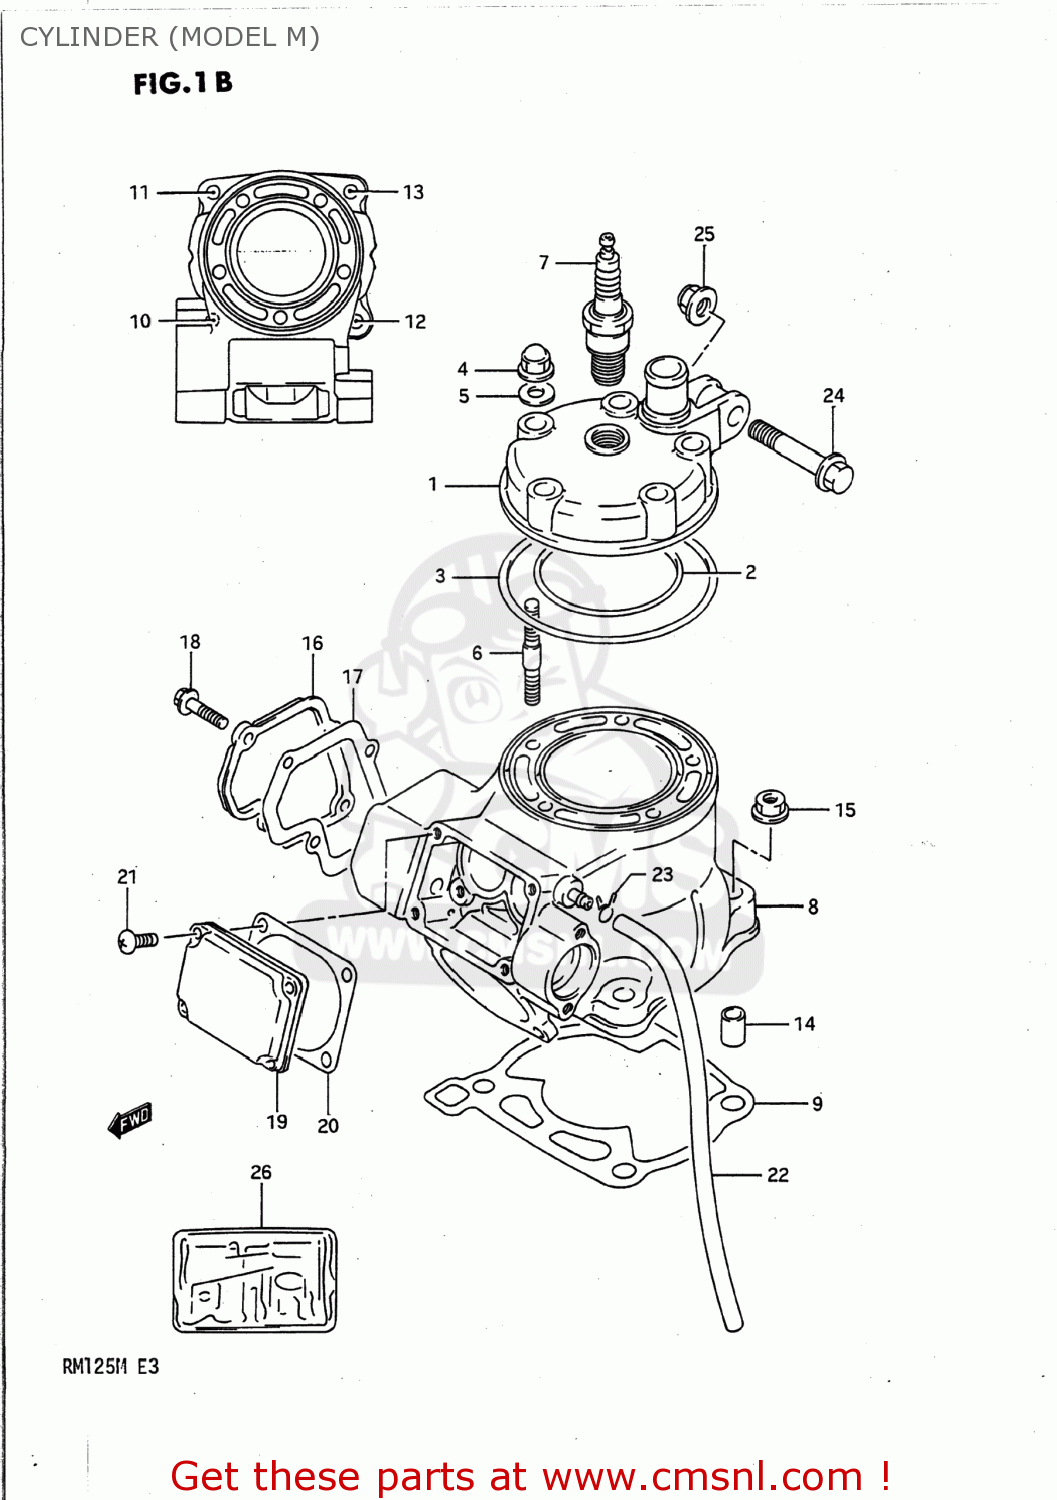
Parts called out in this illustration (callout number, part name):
1	HEAD,CYLINDER
2	O RING,CYLINDER HEAD NO.1
3	O RING,CYLINDER HEAD NO.2
4	NUT
5	GASKET(8.5X17X2.3) (NAS)
6	BOLT,STUD
7	SPARK PLUG W27ES-ZU
8	CYLINDER
9	GASKET,CYLINDER (NAS)
10	STUD 8X25
11	BOLT,STUD
12	STUD BOLT
13	BOLT,STUD
14	PIN
15	NUT
16	COVER,CYLINDER NO.1
17	GASKET,CYLINDER COVER (MCA)
18	BOLT
19	COVER,CYLINDER NO.2
20	GASKET,CYLINDER COVER NO.2 (NAS)
21	SCREW
22	HOSE
23	CLAMP
24	BOLT(8X41)
25	NUT
26	GASKET SET (MCA)
